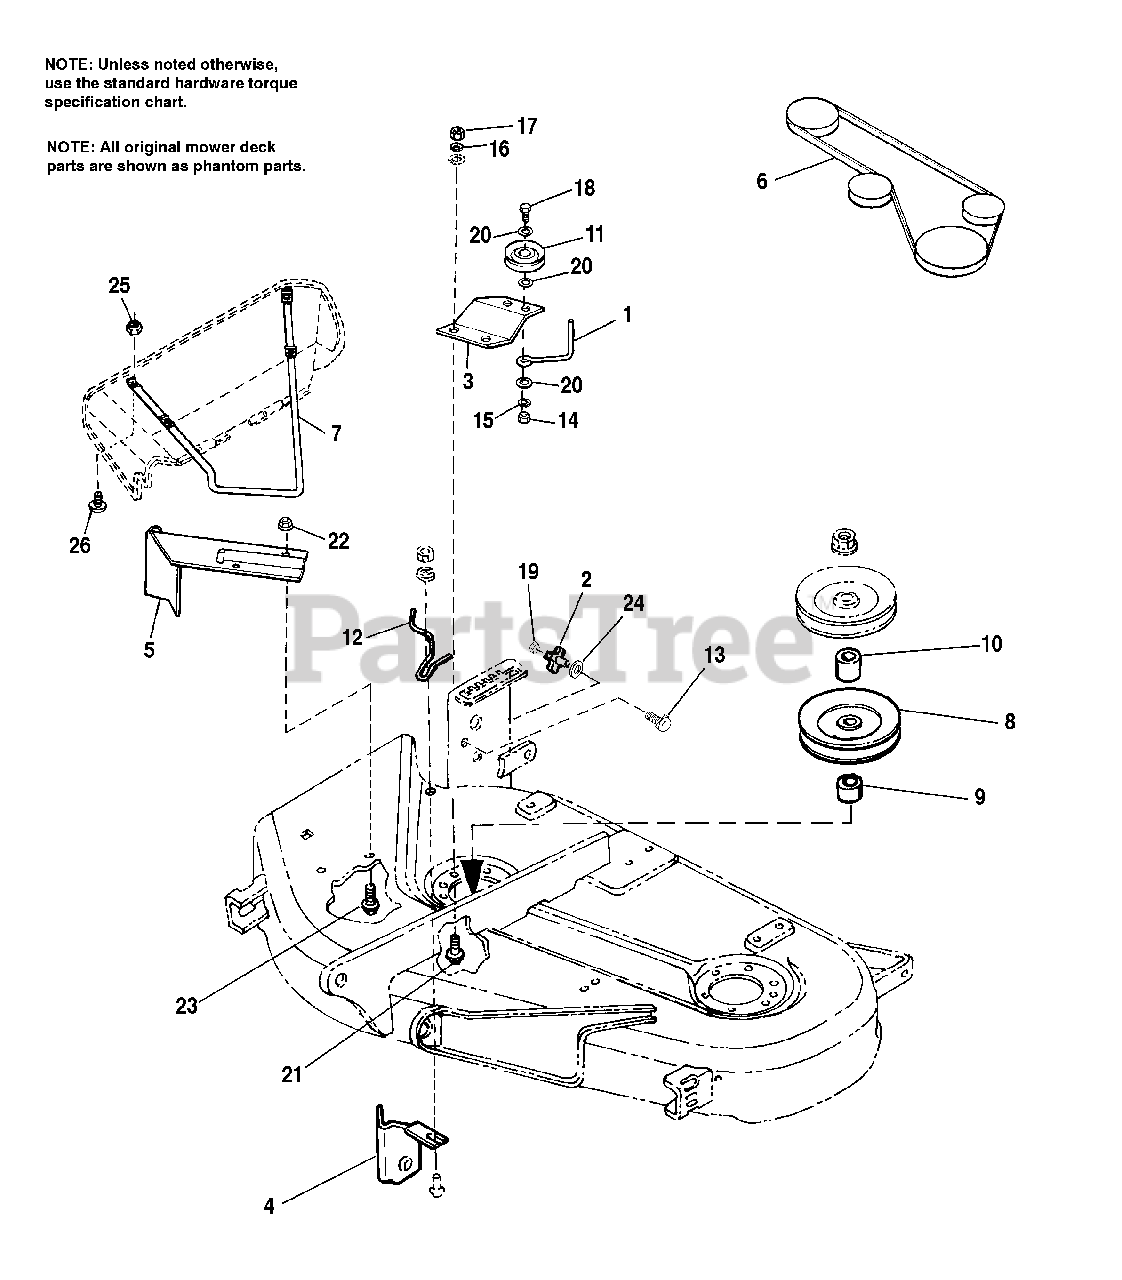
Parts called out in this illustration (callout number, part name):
3	BRACKET, Idler, Turbo
4	BRACKET ASSY., Cut-off
5	PIVOT ASSY., 38"
7	ROD, Deflector
9	HUB, Pulley, Short, Splined
10	HUB, Pulley, Long
11	PULLEY ASSY., Idler
12	SPRING LATCH
13	CARRIAGE BOLT, 5/16-18 x 1-1/2
14	NUT, Hex, 3/8-16
15	LOCKWASHER, 3/8
16	LOCKWASHER, 5/16
17	NUT, Hex, 5/16-18
18	CAPSCREW, 3/8-16 x 1-1/4
19	LOCKNUT
20	WASHER, Flat, 3/8
21	SCREW, Taptite, 5/16-18 x 1-1/2
22	NUT, Hex, Flange, Whizlock, 5/16-18
23	CARRIAGE BOLT, 5/16-18 x 3/4
24	WASHER, Flat
25	NUT, Nylock, #10-24
26	SCREW, Truss Hd., #10-24 x 3/4
